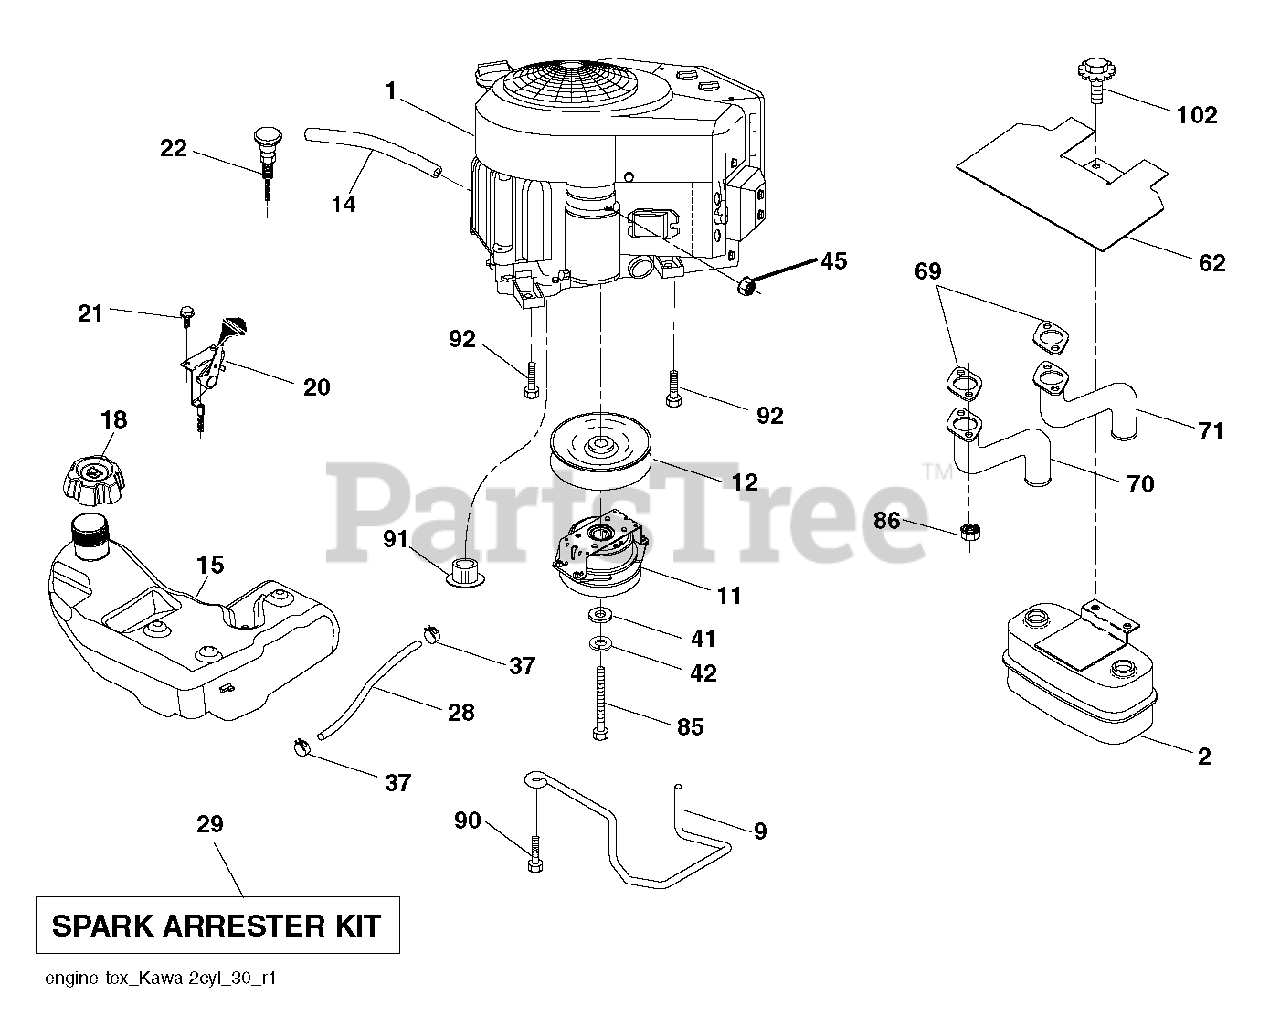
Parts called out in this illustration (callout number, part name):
2	MUFFLER.ASM.TWN.EXTNDED.DFLCTR
9	KEEPER BELT ENGINE
11	CLUTCH.OGURA.5.0PD.GT1.5A-EH07
12	PULLEY.ENGINE.TUFFTORQ
14	TUBE, DRAIN OIL ASM.
15	TANK.FUEL.4GAL
18	CAP.FL.R.3'N/CARB.H.CROWN.498
20	CONTROL.THROTTLE.COBRA.BLACK
21	SCREW.#10 X 0.750.BOS
22	CONTROL.CHOKE.ERGO.PUSH-IN.BLA
28	REPL BY 532 00 85-43
29	KIT.SPARK ARRESTOR 794945 B&S
37	HOSE CLAMP
42	LOCKWASHER
45	NUT
62	SHIELD.HEAT.MUFFLER
70	TUBE.EXHAUST.LH.FR961/FR730
71	TUBE.EXHAUST.RH.FR961/FR730
85	BOLT HEX 7/16-20 X 3.75 GR. 5
86	NUT.HEX.FLANGE.TOPLOCK
90	SCREW 3/8-16X1
91	BUSHING.1.375OD
92	SCREW 3/8-16X1
102	SCREW
